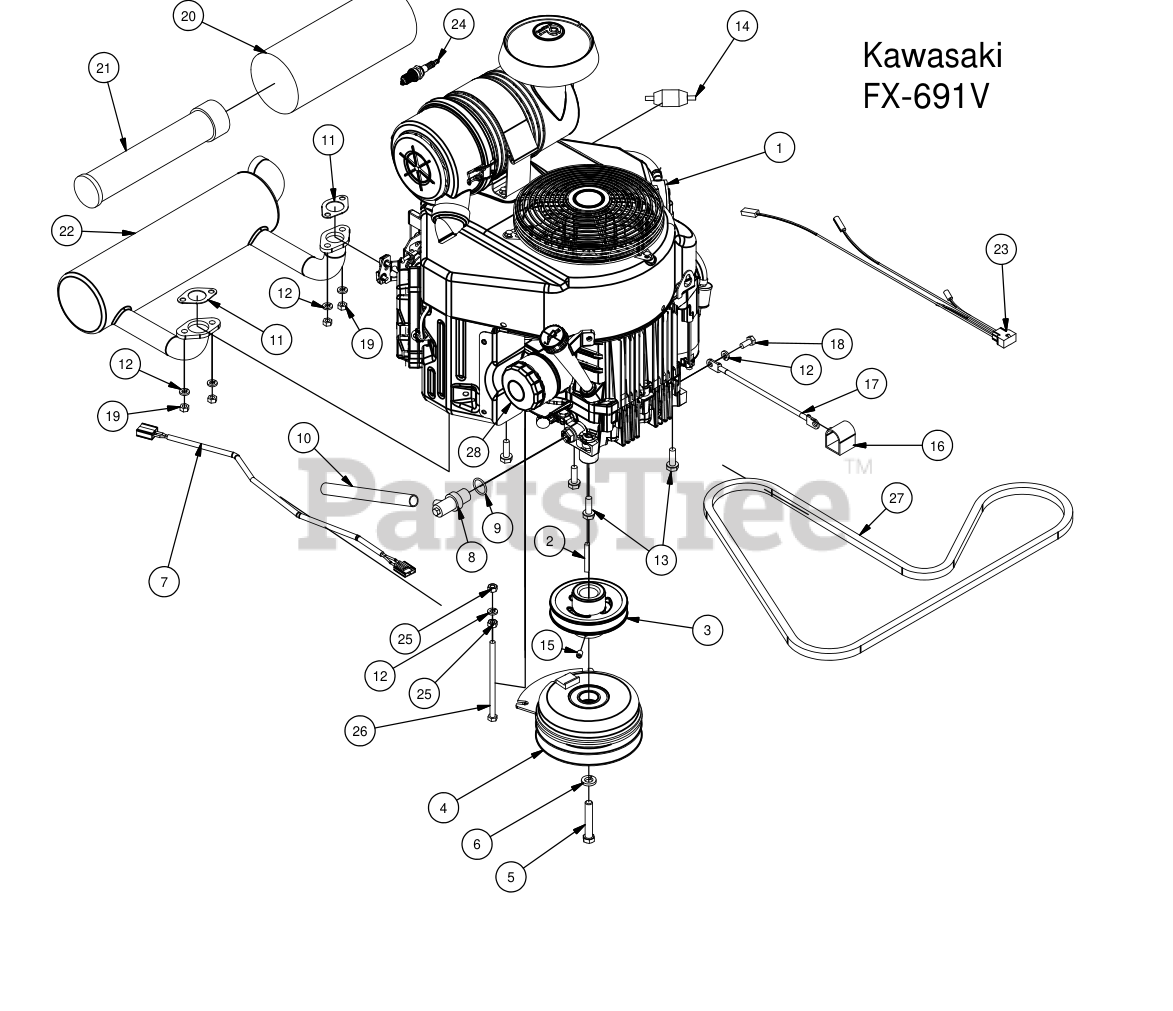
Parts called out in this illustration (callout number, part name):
2	1/4 x 2 Square key Stock
3	4 3/4 Motor Pulley
4	Clutch Assembly
5	7/16" x 2 1/2" Hex Bolt
6	7/16" Lock Washer
7	Clutch Pigtail
10	1/2 Clear Braded Hose Priced/Foot
11	Exhaust Gasket
12	5/16" Lock Washer
13	3/8 x 1 1/8 bolt
14	Universal Inline Fuel Filter
15	5/16 Set Screw
16	Black Boot For Ground Cable
17	Ground Cable
18	M8x1.20x20MM Hex head bolt
19	M8-1.25 Zinc Nut
20	Canister Air Filter- Outer
21	Canister Air Filter- Inner
22	Exhaust Kawasaki FS/FR
23	Harness Adaptor
24	Spark Plug - Kawasaki
26	5/16-18 x 5-1/2 GR 5 Hex Bolt
28	Oil Filter
